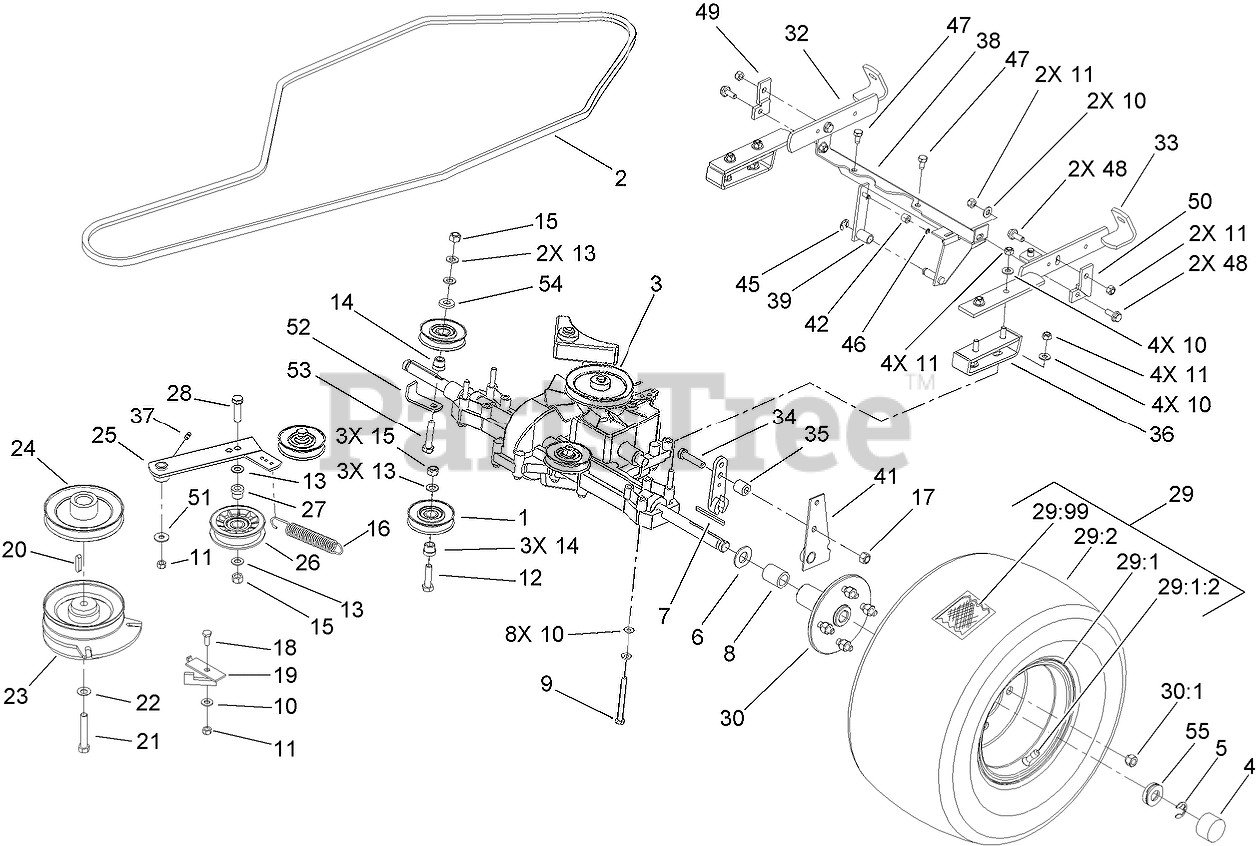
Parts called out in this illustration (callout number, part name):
1	PULLEY-IDLER
2	V-BELT-TRACTION
3	TRANSMISSION
4	CAP-HUB
5	CLIP-SPRING
6	WASHER
7	KEY-SQUARE
8	SPACER-AXLE
9	SCREW-HH
10	WASHER-PLAIN
11	NUT-LOCK, NI
12	SCREW-HH
13	WASHER-FLAT
14	BUSHING-IDLER
15	NUT-LOCK, NI
16	SPRING
17	NUT-LOCK, NI
18	SCREW-HH
19	RETAINER
20	KEY-SQUARE
21	SCREW-HH
22	WASHER-SPRING, BELLEVILLE
23	CLUTCH-ELECTRIC
24	PULLEY-ENGINE
25	ARM-IDLER
26	PULLEY-IDLER
27	BUSHING-IDLER
28	SCREW-HH
29	REAR WHEEL COMPLETE
29:1	RIM ASSEMBLY
29:1:2	STEM-VALVE
29:2	TIRE
29:99	Tube
30	HUB-WHEEL
30:1	NUT-LUG
32	Bracket-Right
33	Bracket-Left
34	SCREW-HH
35	SLEEVE
36	BRACKET-SUPPORT
37	FITTING-GREASE
38	Bar ASM
39	Arm-Switch
42	Roller
45	Stirrup
46	STIRRUP
47	SCREW-THREAD FORMING
48	SCREW-HEX
49	BRACKET-RIGHT
50	BRACKET-LEFT
51	WASHER-PLAIN
52	RETAINER-BELT
53	SCREW-HH
54	WASHER-FLAT
55	RETAINER-CAP, HUB
